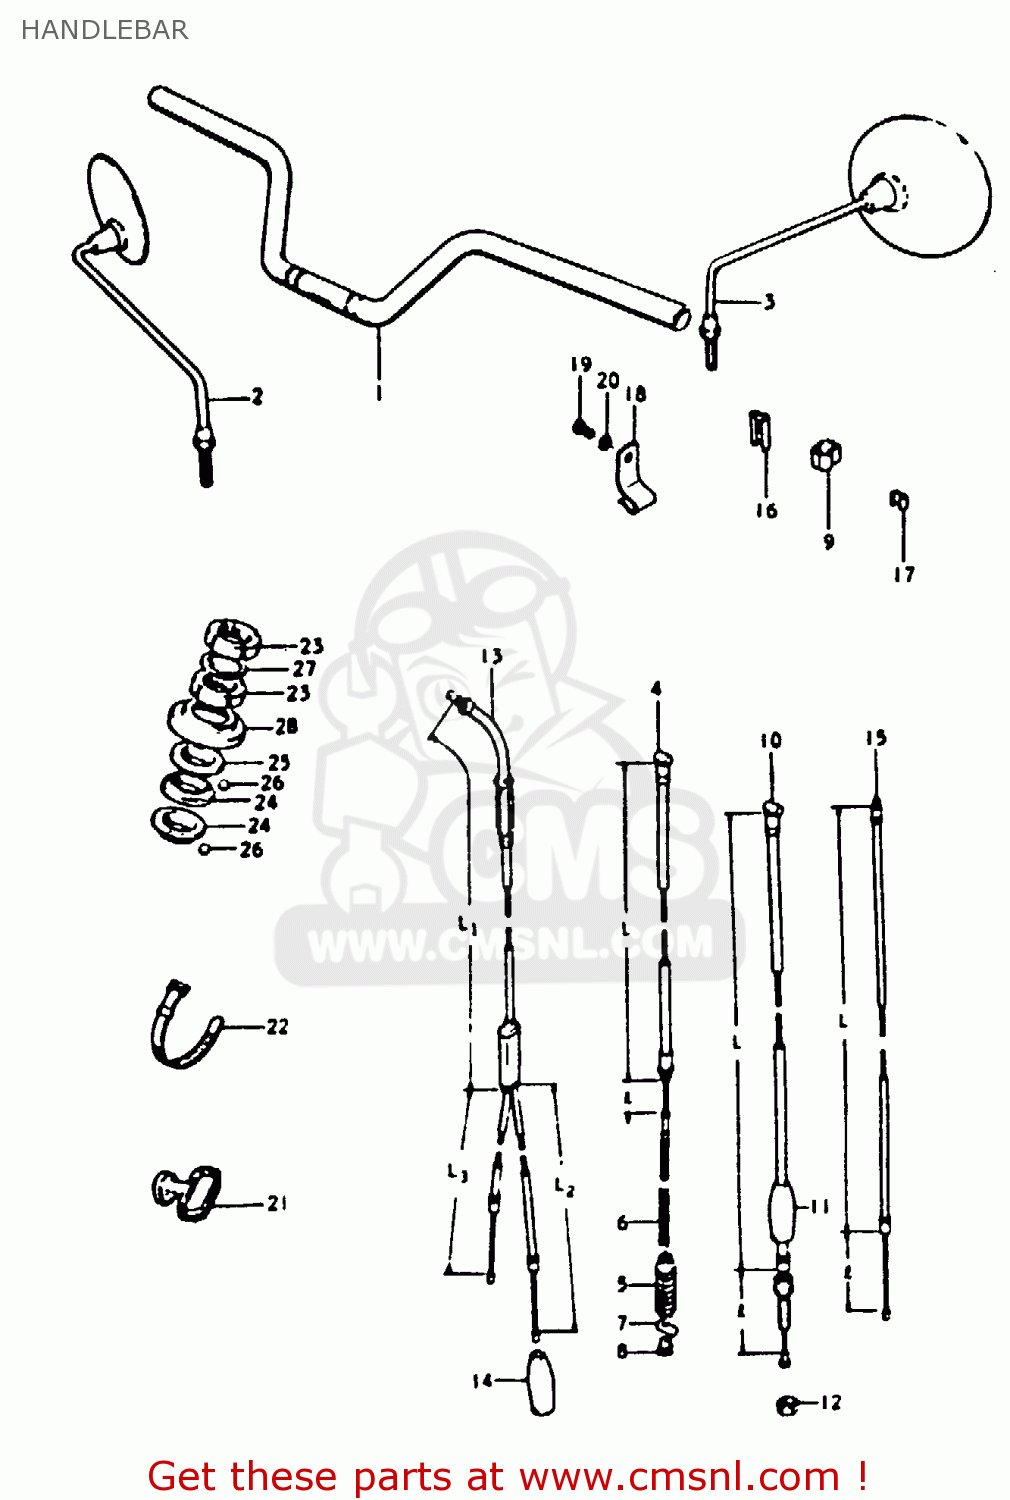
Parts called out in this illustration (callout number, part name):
2	MIRROR ASSEMBLY,RIGHT
3	MIRROR ASSEMBLY,LEFT
4	CABLE ASSEMBLY,FRONT BRAKE
5	SEAL,DUST(7X16X75)
6	SPRING
7	PIN,10X19
8	NUT
11	SEAL,DUST(7X18X30)
12	NUT
14	SEAL,DUST(7X18X30)
16	CLIP
17	CLIP
18	CLAMP
19	BOLT
20	LOCK WASHER
23	NUT
24	RACE,STEERING INNER UPR
25	LACE,STEERING OUTER UPR
26	BALL
27	WASHER
28	DUST SEAL,STEERING UPR
